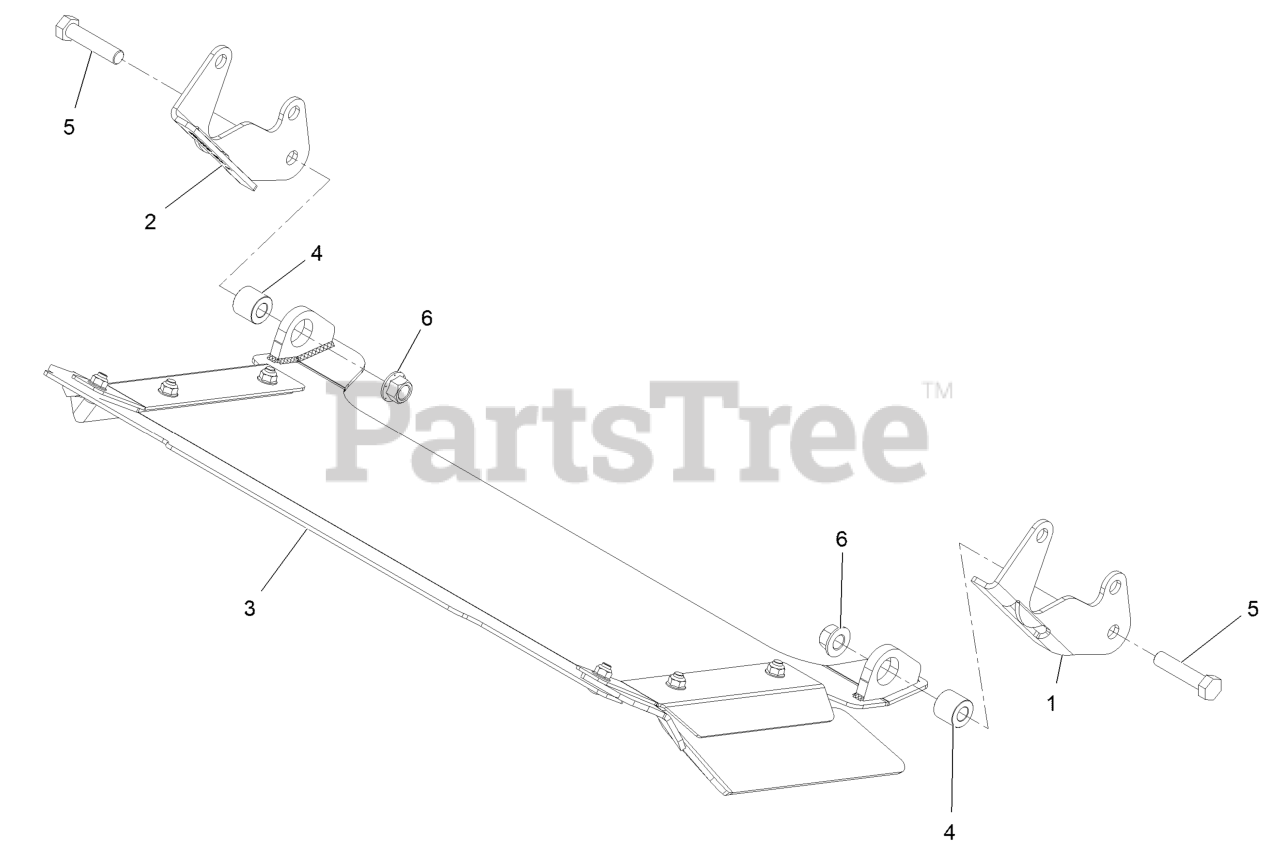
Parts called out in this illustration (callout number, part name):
1	Bracket-Discharge Mount, LH
2	Bracket-Discharge Mount, RH
3	Discharge Tunnel ASM
4	Bushing-Sleeve
5	Screw-HH 1/2-13 X 2 1/4
6	Nut-Lock 1/2-13
